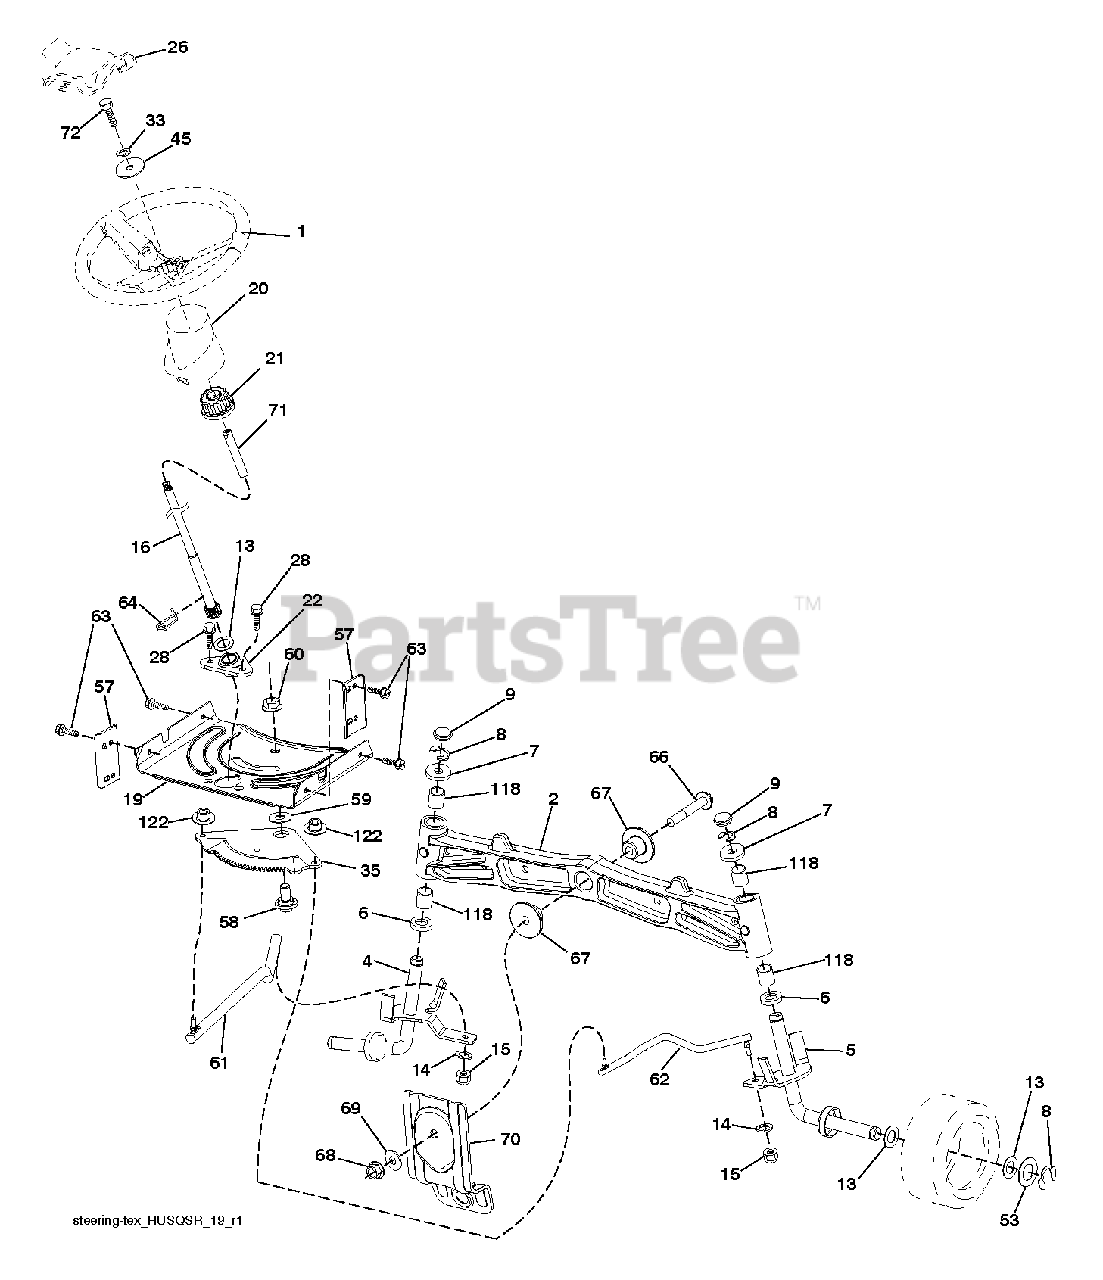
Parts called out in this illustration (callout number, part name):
1	WHEEL, STEERING
4	SPINDLE.WELDED.LH.15"T
5	SPINDLE.WELDED.RH.15"T
6	BRNG T
14	WASHER, LOCK 3/8
15	NUT CROWNLOCK 3/8-24
19	PLATE.STEER.DDL.NLT/NG
21	ADAPTER, WHEEL STNG
22	STEERING.SUPT.LOWER.
26	INSERT, WHEEL STEERING
28	SCREW, 3/8-16X3/4
35	GEAR.SECTOR.PLATE.DDL.
58	BOLT.SHOULDER.SECTOR.P
59	WASHER.THURST.SECTOR.S
60	NUT FLANGE LOCK 5/8-11
61	DRAGLINK.LH.BALLSTUD.D
62	DRAGLINK.RH.BALLSTUD.D
63	SCREW
64	RETAINER.CLIP.SPRING.S
66	BOLT HEX FGHD 7/16-14 X 3 SERR
67	BUSHING.PM.FRONT AXLE
68	NUT.LOCK.FLANGE.7/16
69	WASHER.1.5X.505X.118
70	BRKT.DECK.SUSPENSION.F
